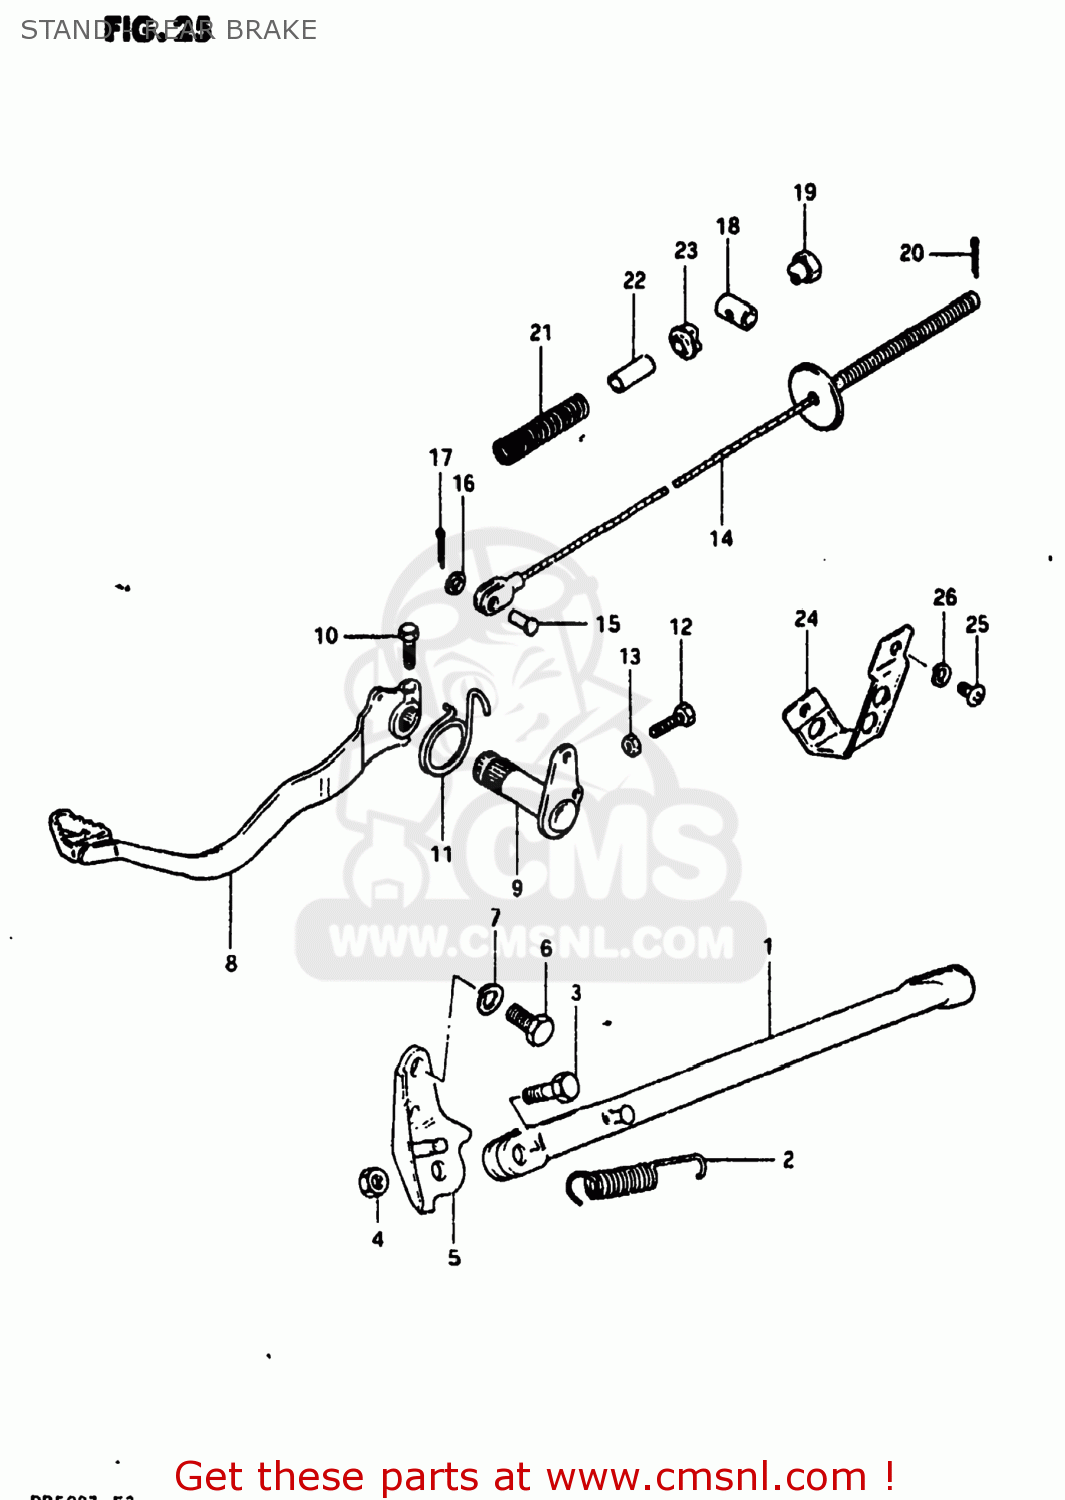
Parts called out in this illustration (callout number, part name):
1	STAND,SIDE
2	SPRING
3	BOLT(10X30)
4	NUT
5	BRACKET,PROP STAND
6	BOLT(10X19)
7	LOCK WASHER
8	PEDAL,BRAKE
9	ARM,BRAKE PEDAL
10	BOLT
11	SPRING
12	BOLT(6X23)
13	NUT
14	CABLE,RR BRAKE
15	PIN(L:17.5)
16	WASHER
17	PIN
18	PIN,BRAKE CABLE ADJUSTER
19	NUT
20	PIN
21	SPRING
22	CUSHION,FR GRILLE,UPPER
23	CUSHION
24	GUIDE,CABLE
25	SCREW
26	LOCK WASHER
